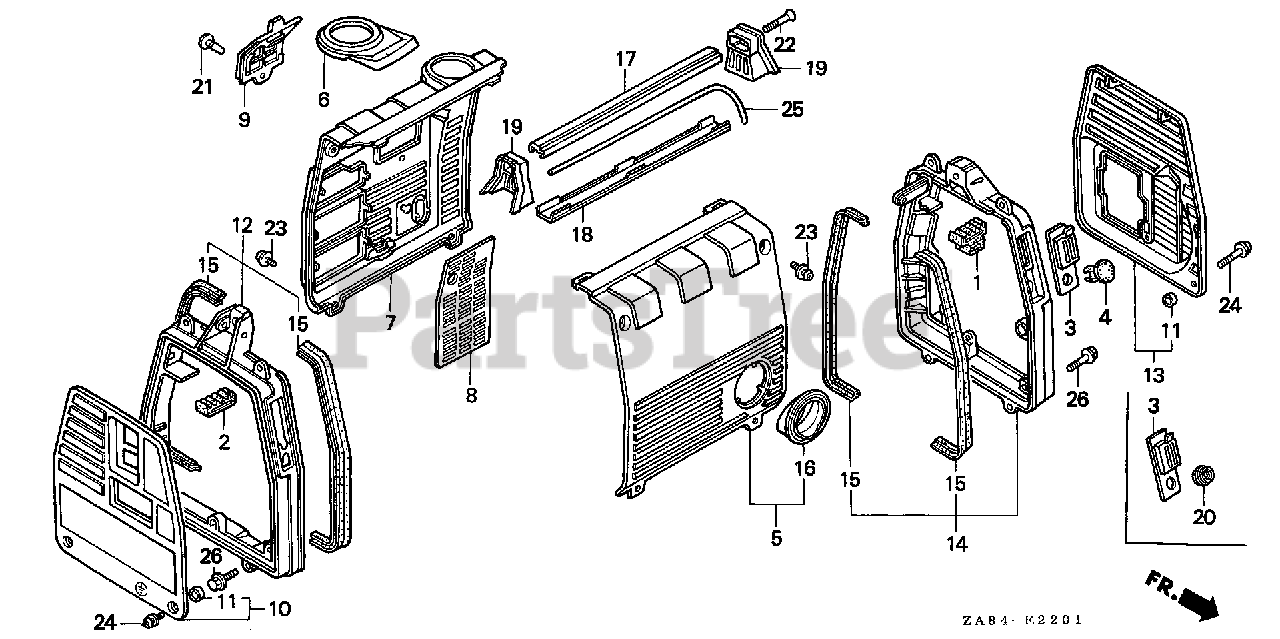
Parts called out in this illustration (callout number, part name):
1	RUBBER, R. RR. TANK MOUNTING SIDE
2	RUBBER, L. RR. TANK MOUNTING SIDE
3	COVER, ENGINE SWITCH GUIDE
4	CAP, ENGINE SWITCH GUIDE
5	COVER ASSY., FR.
6	GUIDE, TANK CAP
7	COVER, RR.
7	COVER, RR. *R8* (BRIGHT RED)
8	GRID, RR. COVER
9	COVER, PLUG CHECK
10	COVER, L. SIDE
11	COLLAR, SIDE COVER
12	FRAME, L. SIDE
13	COVER, R. SIDE
14	FRAME, R. SIDE
15	RUBBER, SIDE SEALING
16	RUBBER, OIL CHECK
17	BAR, CARRYING HANDLE
18	COVER, HANDLE
19	COVER, HANDLE SIDE
20	NUT (15MM)
21	CLIP (5.0MM)
22	SCREW, OVAL (6X25)
23	SCREW-WASHER (5X10)
24	SCREW-WASHER (5X16)
25	BULK HOSE, VACUUM (3.5X8000) (3.5X210)
26	BOLT, FLANGE (6X20)
